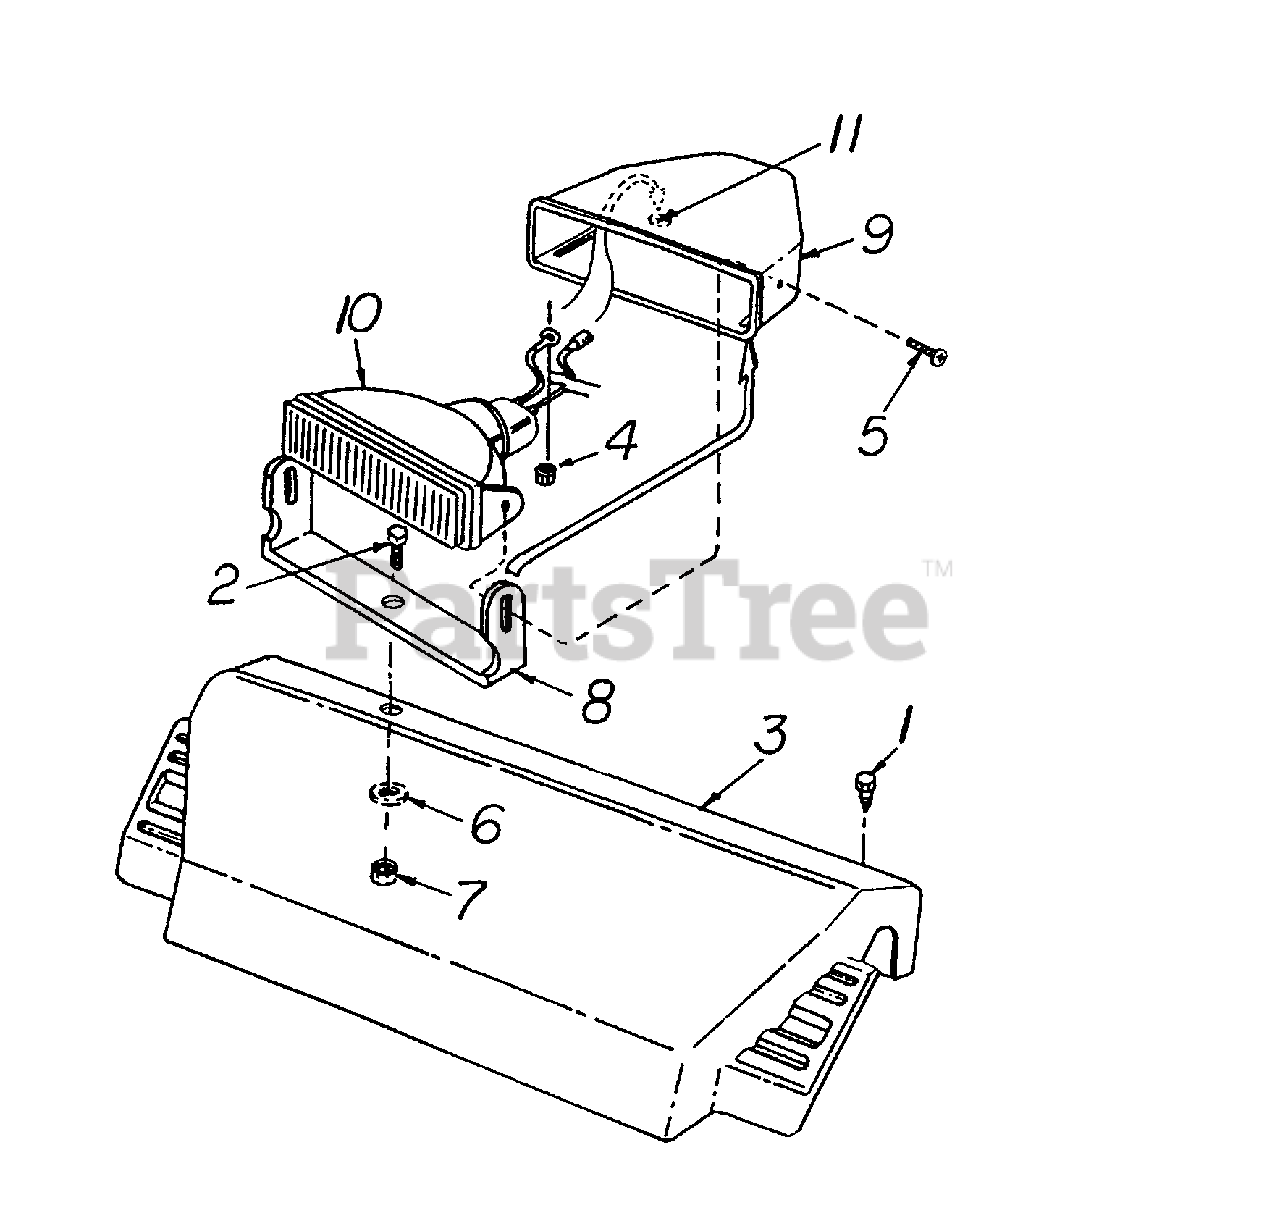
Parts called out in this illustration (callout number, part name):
1	Truss Mach. B-Tapp Scr. #10 x .50
2	Hex Screw 3/8-16 x .75
3	Handle Panel (Black, w/Logo)
4	Sems Hex Nut 1/4-20
5	Phillips Pan Hd. Scr. M4 x 16mm
6	Fl-Washer .385 I.D. x .87 O.d. x .06
7	Hex Ins. Lock Nut 3/8-16
8	Lamp Mounting Brkt.
9	Halogen Lamp Housing
10	Lamp/Lens Hsg. Assembly
11	Grommet
